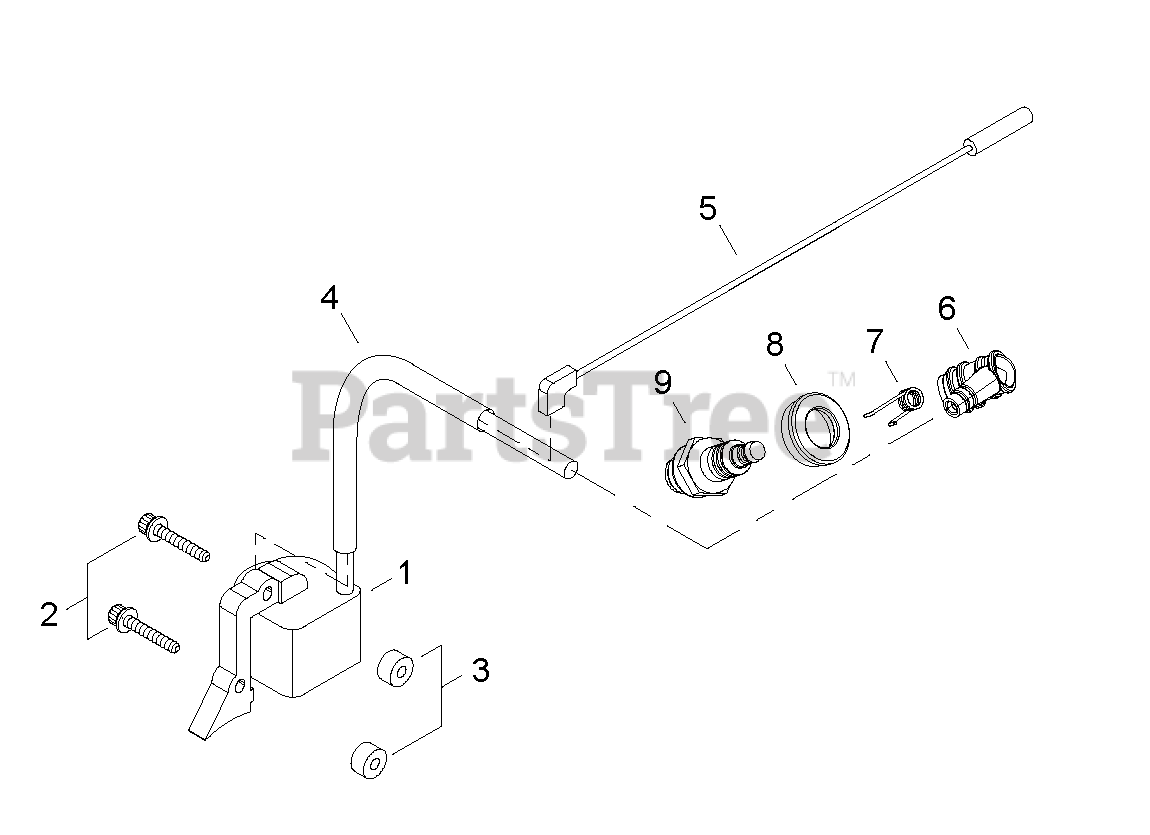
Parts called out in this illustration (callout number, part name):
1	COIL, IGNITION
2	SCREW - 4X20
3	INSULATOR
4	SLEEVE, IGNITION COIL
5	LEAD - IGNITION
6	CAP, SPARK PLUG
7	TERMINAL, SPARK PLUG CAP
8	SEAL, DUST
9	SPARK PLUG -- BPMR-6A
